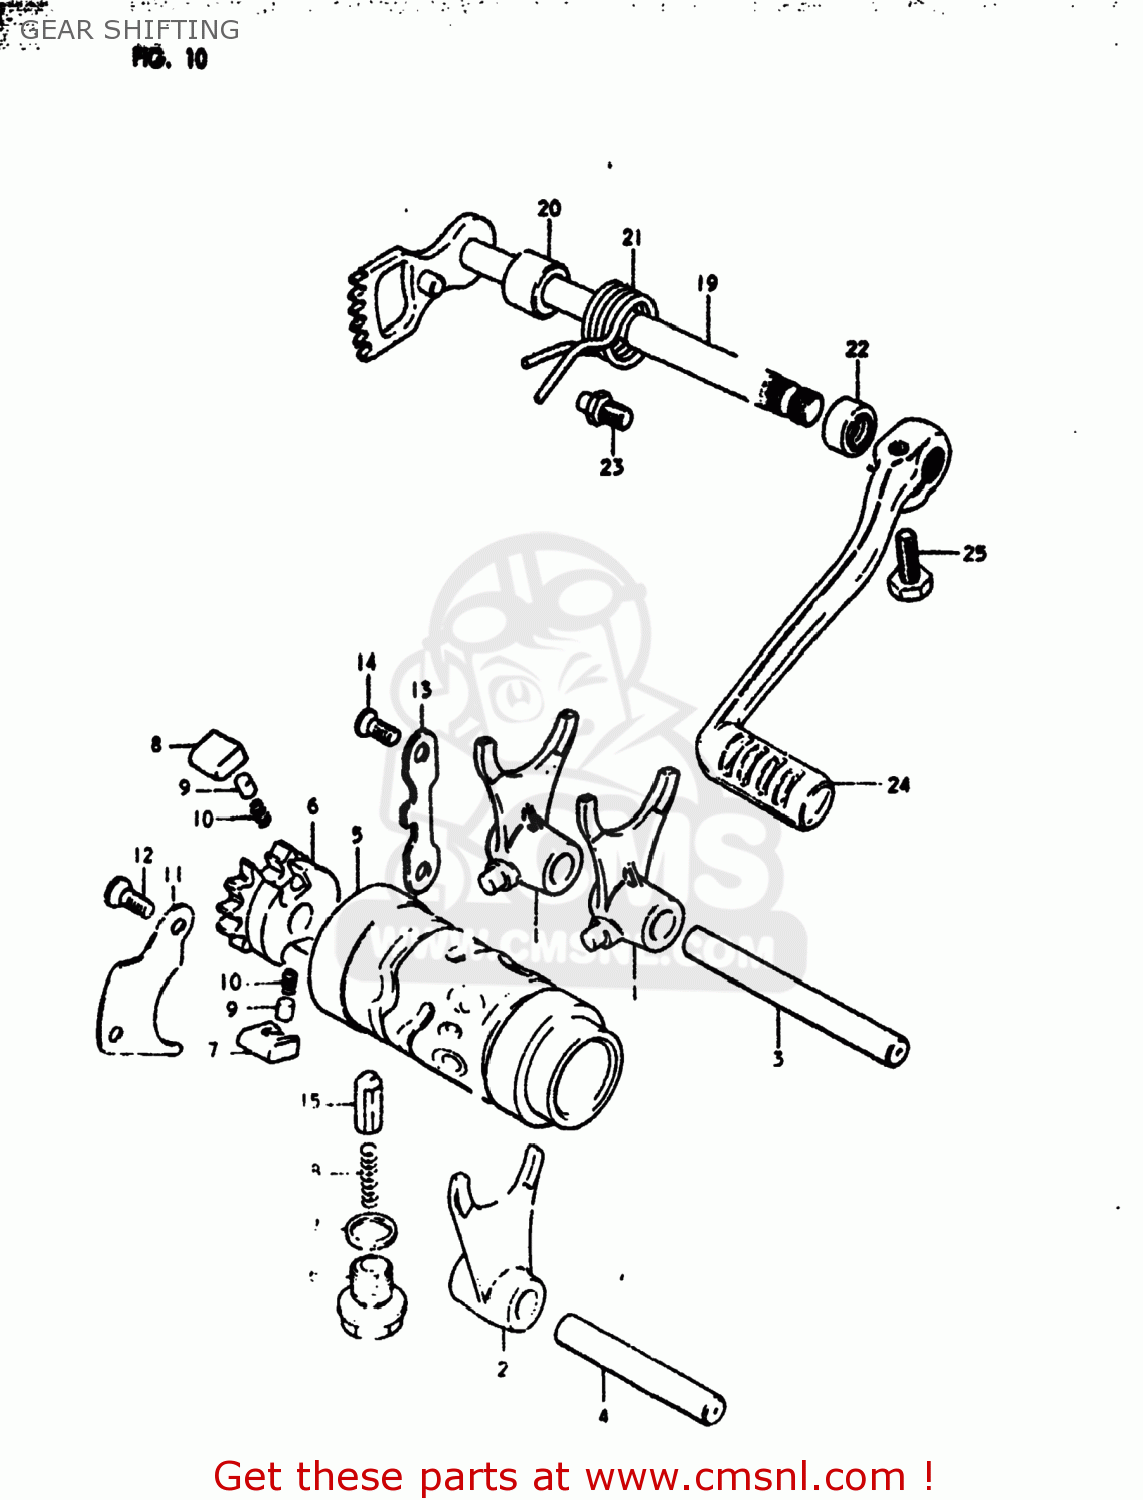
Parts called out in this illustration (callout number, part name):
1	FORK,GEAR SHIFT NO.1
2	FORK,GEAR SHIFT NO.2
3	SHAFT,GEAR SHIFT FORK
4	SHAFT,GEAR SHIFT FORK
5	CAM,GEAR SHIFT
6	RETAINER,GEAR SHIFT CAM
7	PAWL,GEAR SHIFT NO.1
8	PAWL,GEAR SHIFT NO.2
9	PIN(5X8)
10	SPRING
11	LIFTER,GEAR SHIFT PAWL
12	SCREW
13	GUIDE,GEAR SHIFT CAM
14	SCREW
15	STOPPER,GEAR SHIFTING
16	BOLT,GEAR SHAFT CAM STOPPER
17	GASKET(14X19.2X2) (NAS)
18	SPRING
19	SHAFT,GEAR SHIFT
20	SPACER(12X20X15.3)
21	SPRING
22	OIL SEAL
23	STOPPER,GEAR SHIFT CAM
24	LEVER,GEAR SHIFT
25	BOLT
